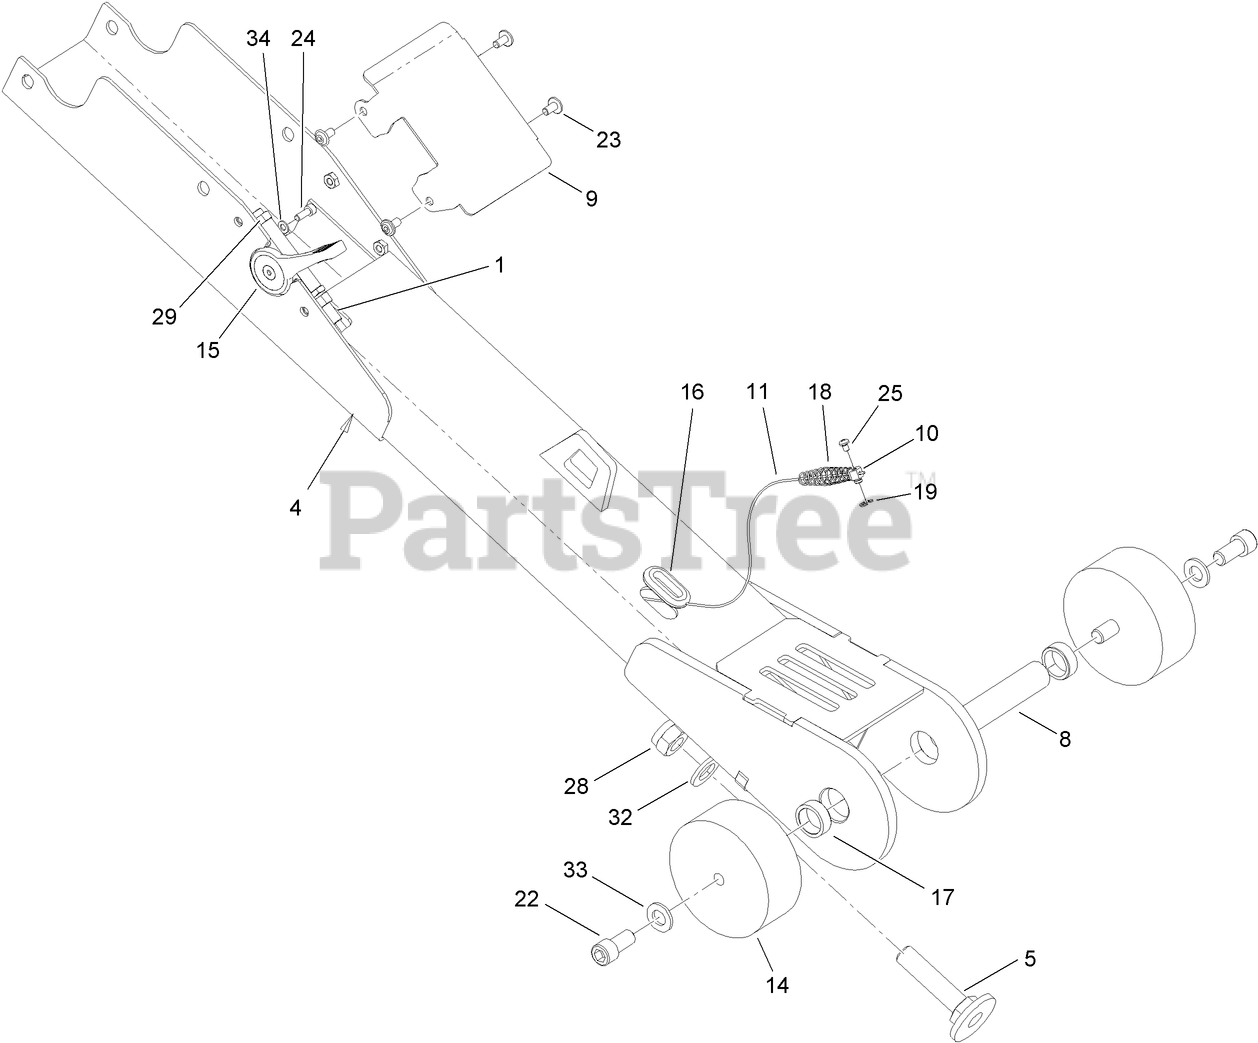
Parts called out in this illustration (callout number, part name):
1	GUIDE-CABLE
5	SCREW-STOP
8	PIN-ARM
10	NUT-WIRE
11	CABLE-THROTTLE
14	MOUNT-RUBBER
15	OBS LEVER
16	GROMMET
17	BUSHING
18	SPRING
19	BAR-RING
32	WASHER
33	WASHER
34	WASHER
